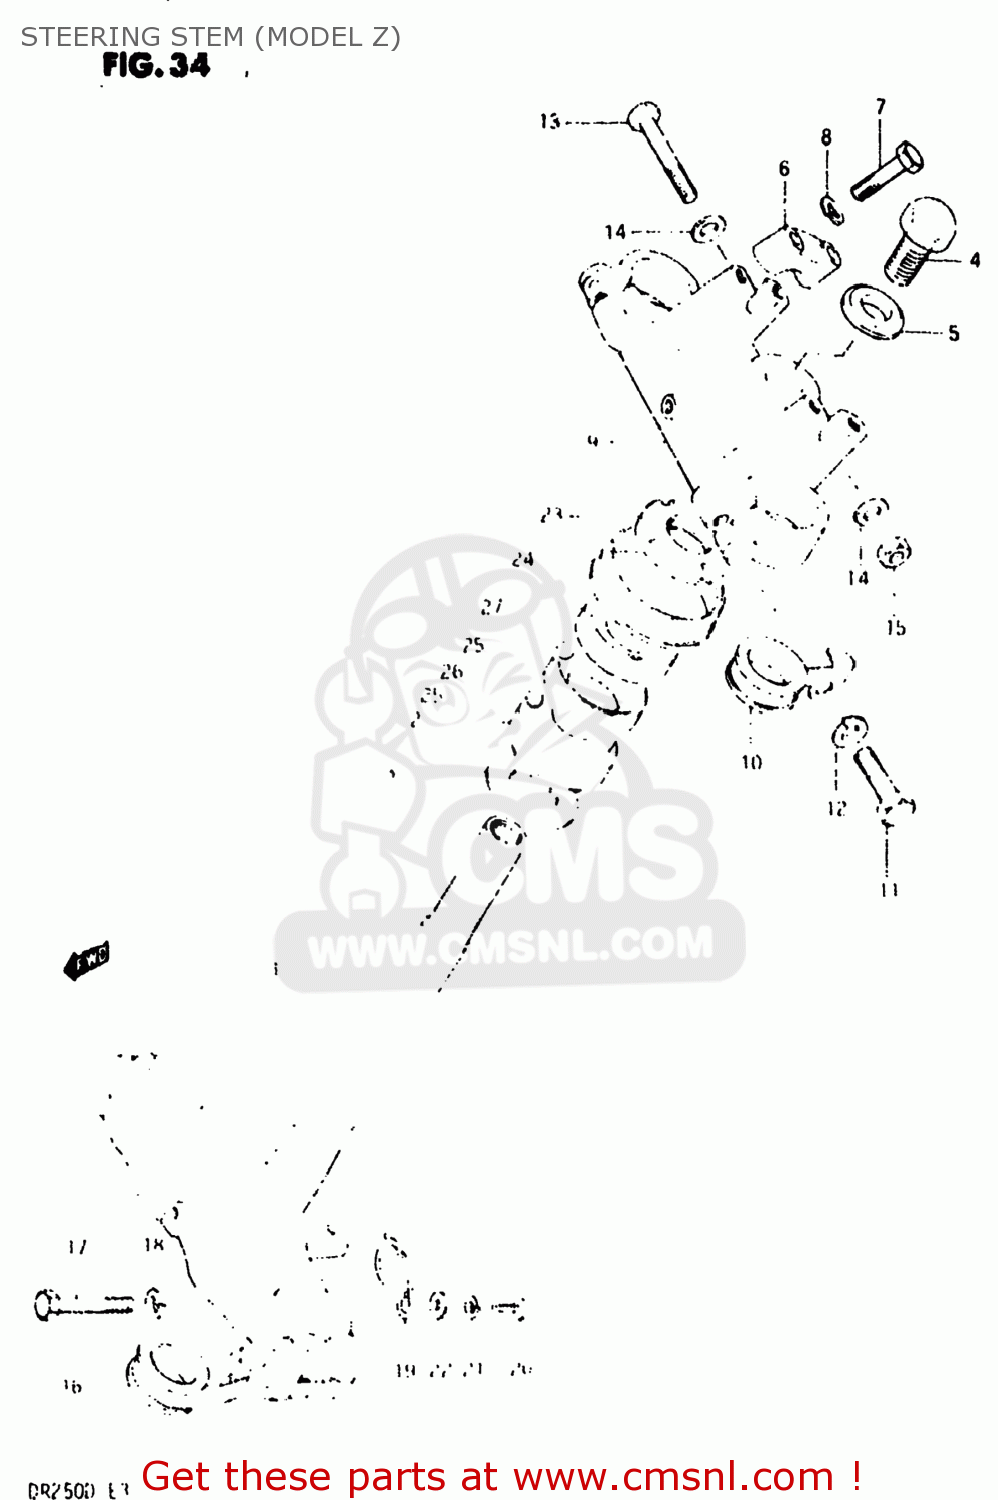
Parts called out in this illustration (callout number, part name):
1	STEM,STEERING
2	BEARING
3	WASHER,THRUST
4	BOLT
5	WASHER
6	HOLDER,HANDLEBAR
7	BOLT
8	LOCK WASHER
9	HEAD,STEERING STEM
10	GUIDE,CABLE
11	BOLT
12	LOCK WASHER
13	BOLT 8X50
14	WASHER
15	NUT
16	GUIDE,CABLE
17	BOLT 8X45
18	LOCK WASHER
19	CLIP
20	SCREW
21	LOCK WASHER
22	WASHER
23	NUT,STEERING STEM
24	SEAL,STEERING UPR DUST
25	BALL
26	RACE,STEERING,INNER,UPPER
27	RACE,STEERING,OUTER,UPPER
